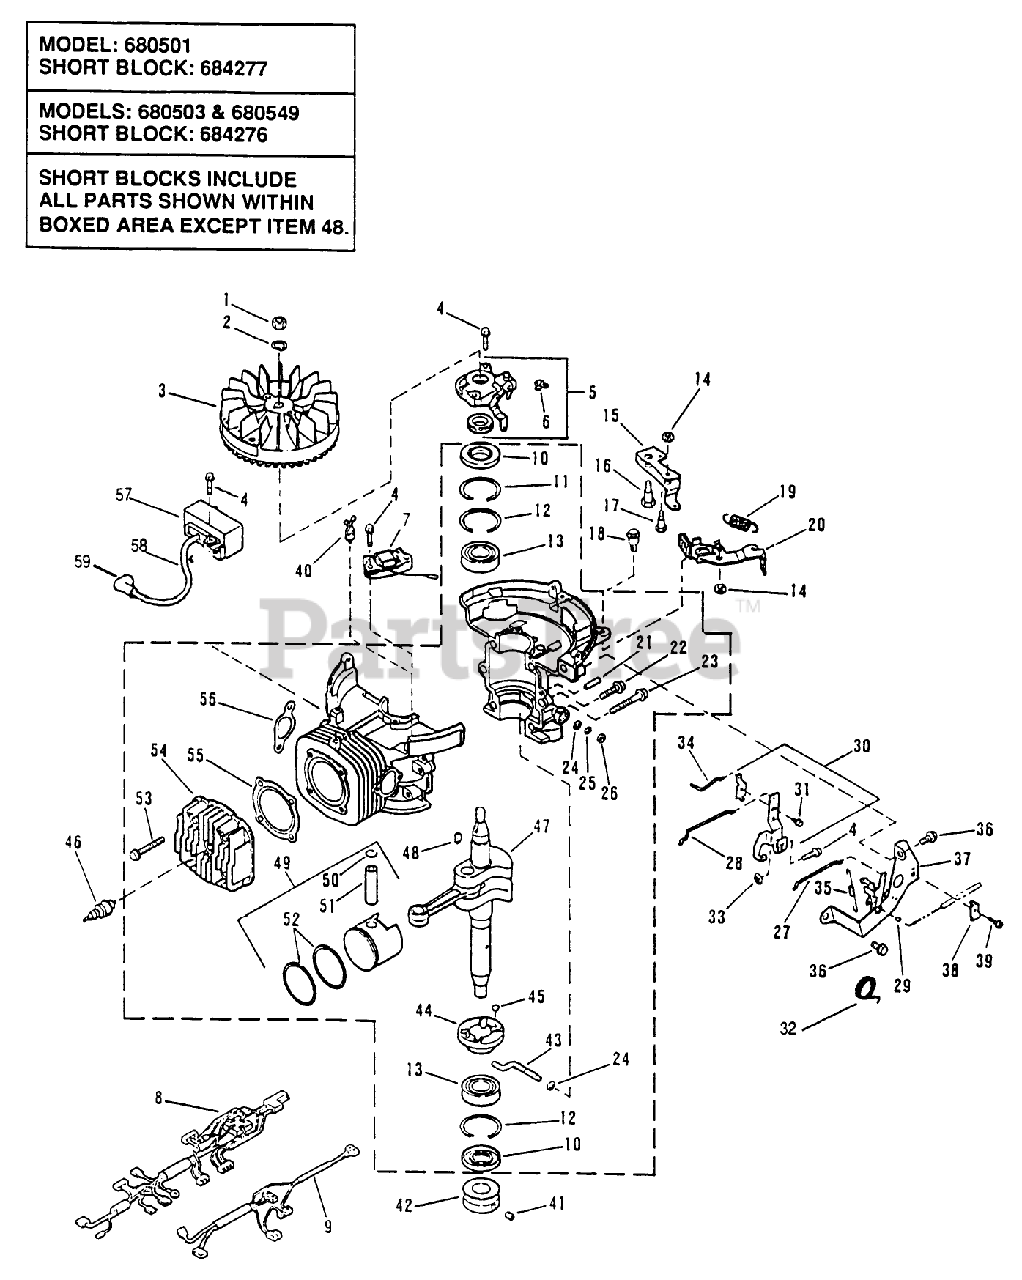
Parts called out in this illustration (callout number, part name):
7	ALTERNATOR ASM
10	SEAL - OIL SM
11	RING-RETAINER SM
13	BEARING-BALL SM
14	LOCKNUT E
15	ACT.BRAKE LVR. SM
16	STUD-SHOULDER SM
19	SPRING-BRAKE
22	SCREW-H.W.HD. F
23	SCREW-HEX W.H. SM
25	RING-RETAINING
26	SEAL - OIL SM
28	ROD-THROTTLE SM
35	SPRING-GOV. SM
37	GOVNR BRKT SM
40	WIRE TIE SM
42	PULLEY-ENGINE
46	SPARK PLUG
52	RING SET S
54	CYLINDER HEAD SM
56	GASKET - EXH SM
58	HI-TENS.LEAD
59	COVER & TERM. AY S
